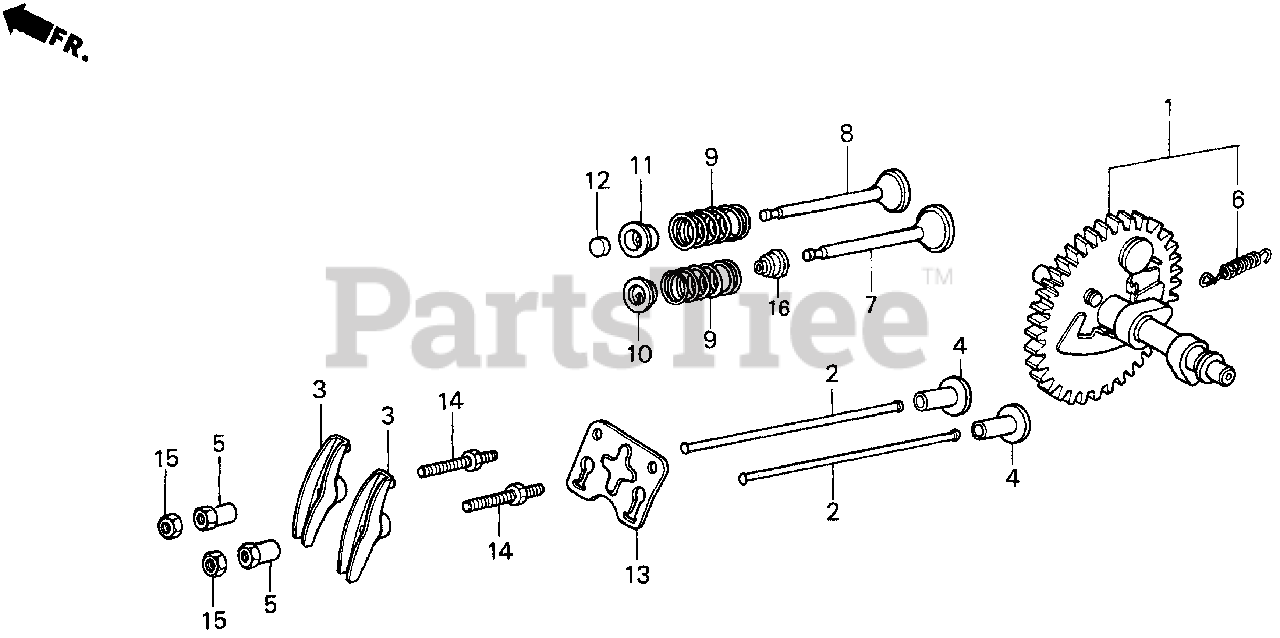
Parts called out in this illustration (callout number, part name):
1	CAMSHAFT ASSY.
2	ROD, PUSH
3	ARM, VALVE ROCKER
4	LIFTER, VALVE
5	PIVOT, ROCKER ARM
6	SPRING, WEIGHT RETURN
7	VALVE, IN.
8	VALVE, EX.
9	SPRING, VALVE
10	RETAINER, IN. VALVE SPRING
11	RETAINER, EX. VALVE SPRING
12	ROTATOR, VALVE
13	PLATE, PUSH ROD GUIDE
14	BOLT, PIVOT (8MM)
15	NUT, PIVOT ADJUSTING
